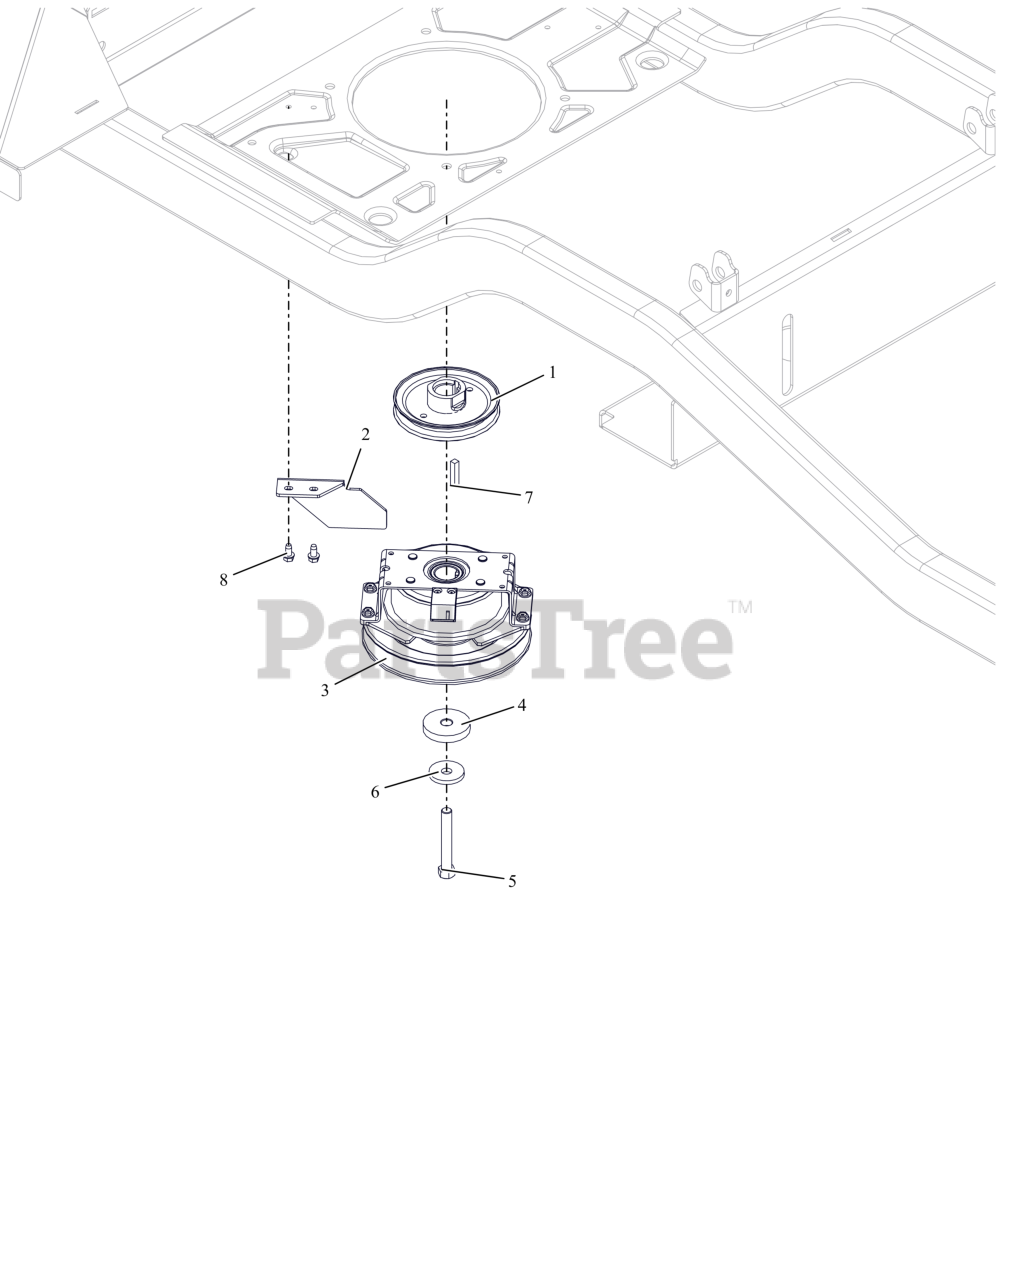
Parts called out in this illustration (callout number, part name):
1	WLDMT,PULLEY-4.50ODX1.003
2	BRKT, CLUTCH STOP HD
3	CLUTCH, OGURA DBL SPRG
4	SPACER, .474/.459X2.00X.350
5	BLT, HEX 0.4375-20X3 G8 ZCC NT
6	WASHER, 7/16" SPRING DISK
7	KEY-SQ .25 X 1.25 X .25 SAE
8	SCR-TAP .25-20X.50 HWH ZCC
